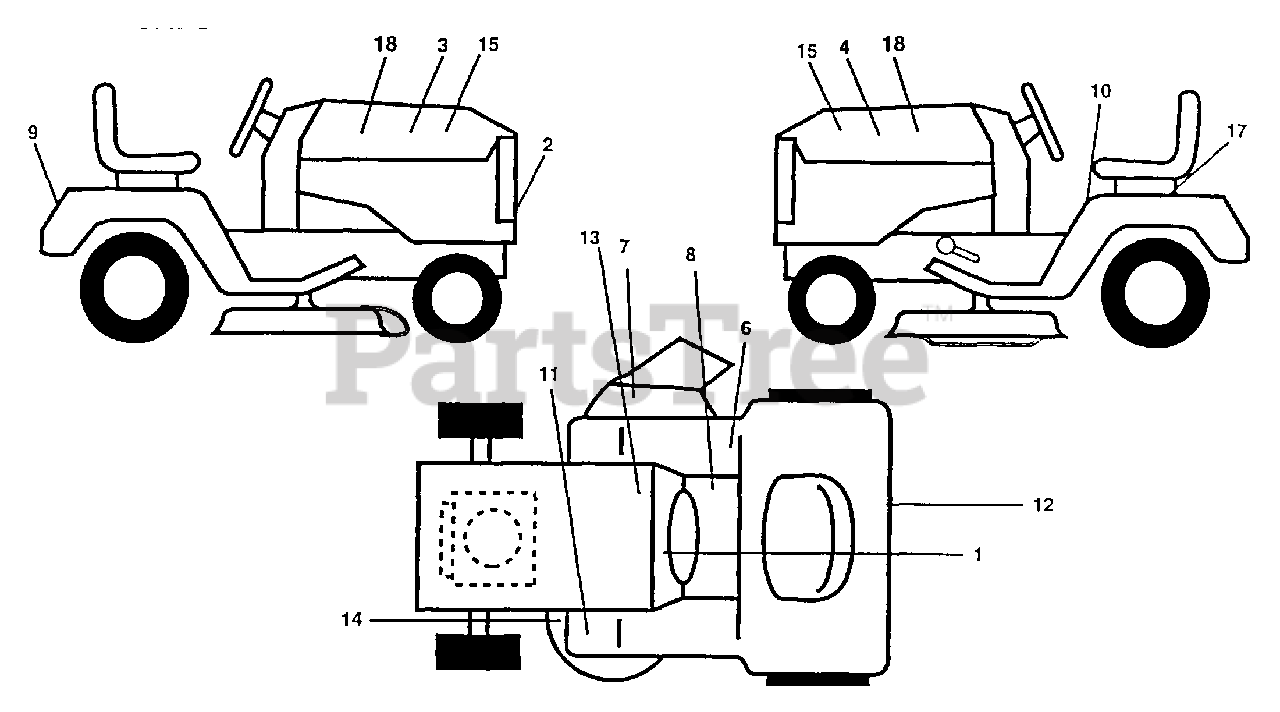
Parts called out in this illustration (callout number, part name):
1	Decal, Operating Instruction
2	Decal, Grille
3	Decal, Hood, RH
4	Decal, Hood, LH
6	Decal, Scl Cold Start Hyd
7	Decal, Warning Multi-Language
8	Decal, Brake Parking Saddle
9	Decal, Fender (AYP part number)
10	Decal, Danger
11	Decal, Clutch/Brake
12	Decal, D-Bar Ctrl. Mvt Hyd YT/GT
13	Decal, Bat. DAN/POI P/L Symbols
14	Decal, V-Belt Schematic (AYP part number)
15	Nameplate Hood Poulan Pro
17	Decal, Cust Asist Poulan Pro
18	Decal, Domed Poulan Pro
